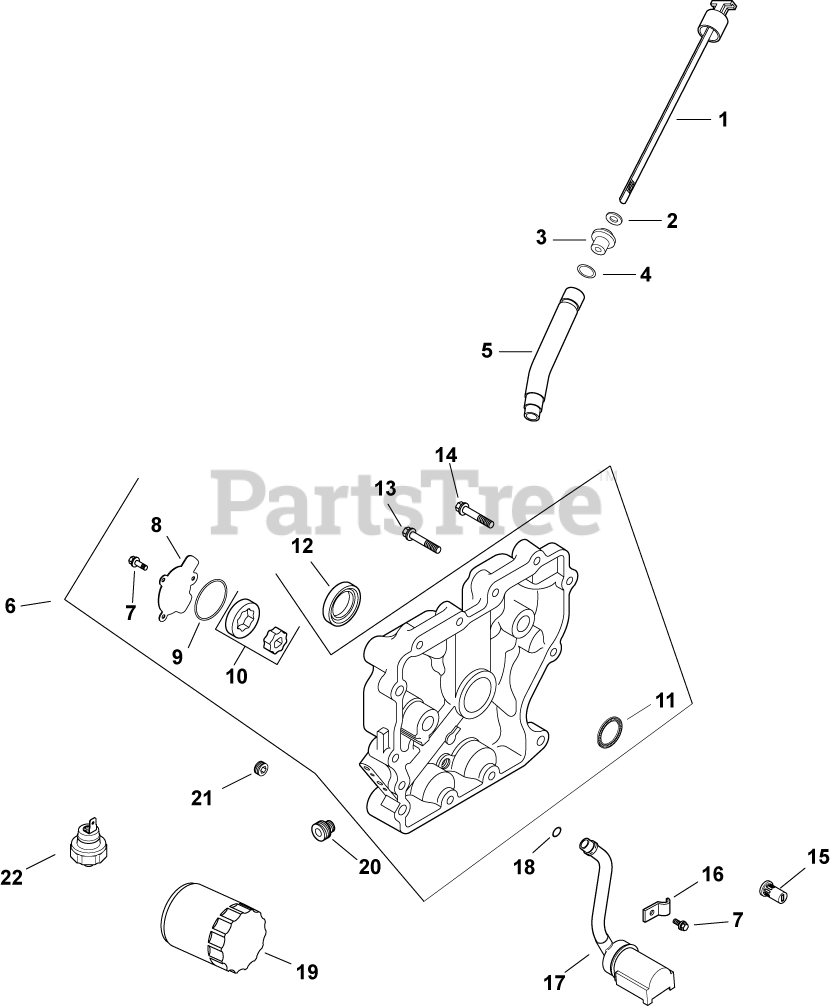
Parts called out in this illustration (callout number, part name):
3	SEAL USE 25 032 13-S
5	TUBE, OIL FILL
6	PLATE, CLOSURE & BEARING
7	SCREW,FLG THD FRM M5X0.8X16-(#25086398S)
8	COVER, OIL PUMP
9	O-RING (1.78" DIA)
10	PUMP ASSEMBLY, OIL
11	BEARING, CRANKSHAFT
12	SEAL, OIL
13	SEAL, OIL
14	SCREW, HEX FLANGE -USE 24 086 17-S
15	VALVE, OIL PRESSURE RELIEF
17	KIT, OIL PICK-UP
18	O-RING (.5" DIA)
19	OIL FILTER
20	NIPPLE, OIL FILTER
21	PLUG, CTSK PIPE 1/8"
22	SENSOR, OIL PSI
